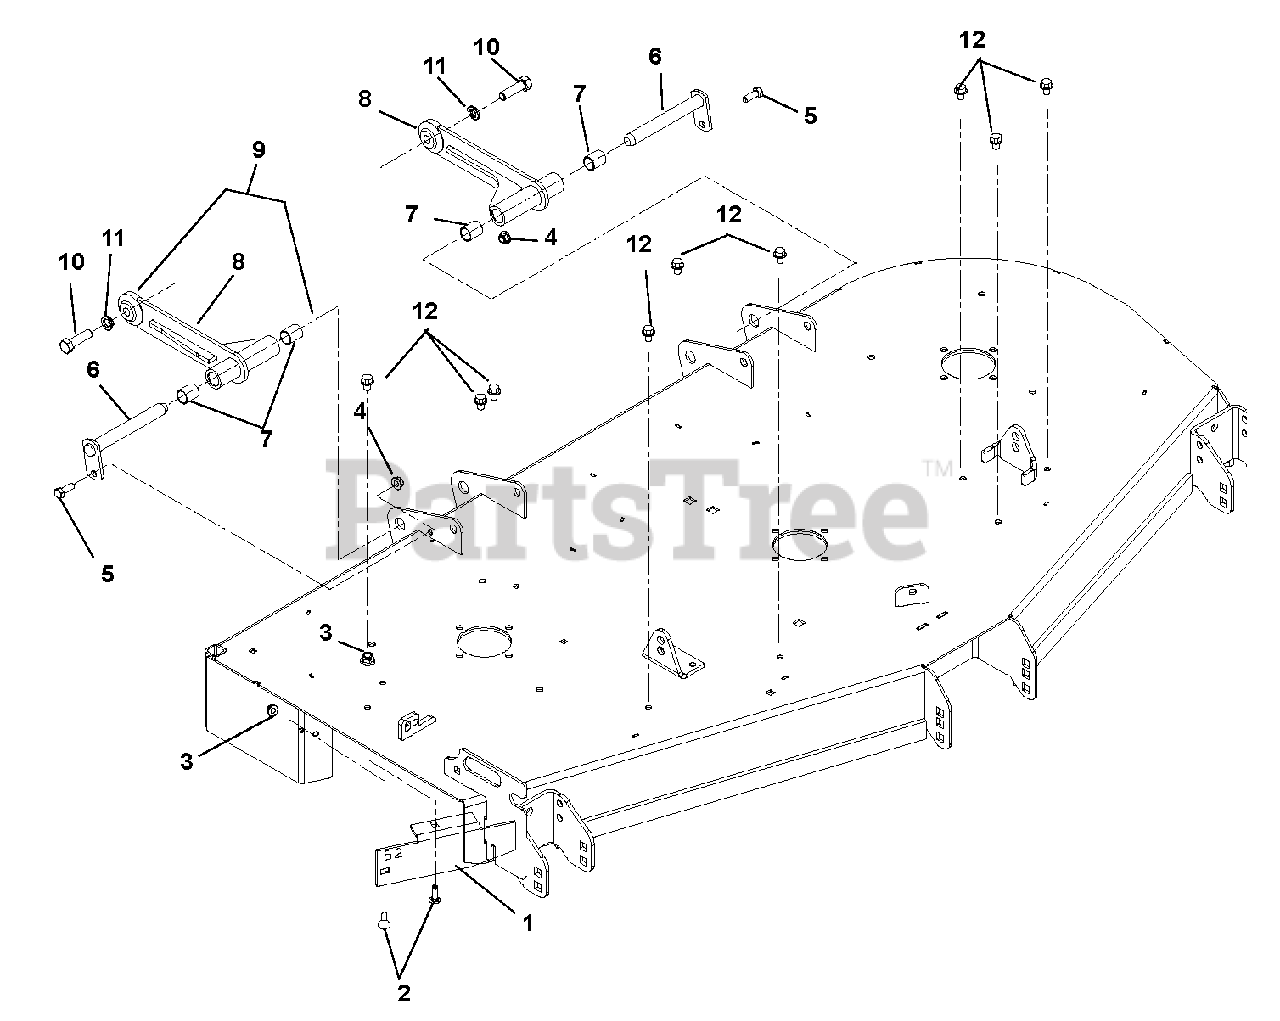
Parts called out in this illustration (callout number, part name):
1	Discharge Baffle, 44" & 48" (991082, 090, 098, 099)
1	Discharge Baffle, 60" (991084, 091, 101)
1	Discharge Baffle, 52" (991083, 100)
2	Bolt, Round Head Square Neck .31-18 x 1.00 Grade 5
3	Nut, .31-18 Nyloc Flange
4	Nut, .38-16 Nyloc Flange
5	Bolt, Hex .38-16 x 1.00 Grade 5
6	Weldment, Mower Mounting Pin
7	Bearing, .75 x .875 x 1.00
8	Deck Pusher Arm Weldment
9	Assembly, Mower Mount Arm (Includes items 7 and 8)
10	Bolt, Hex .50-13 x 1.75 Grade 5 EP80
11	Washer, Locking .50 x .125 Regular
12	Screw, Tapping .38-16 x .50 Hex Washer Head
